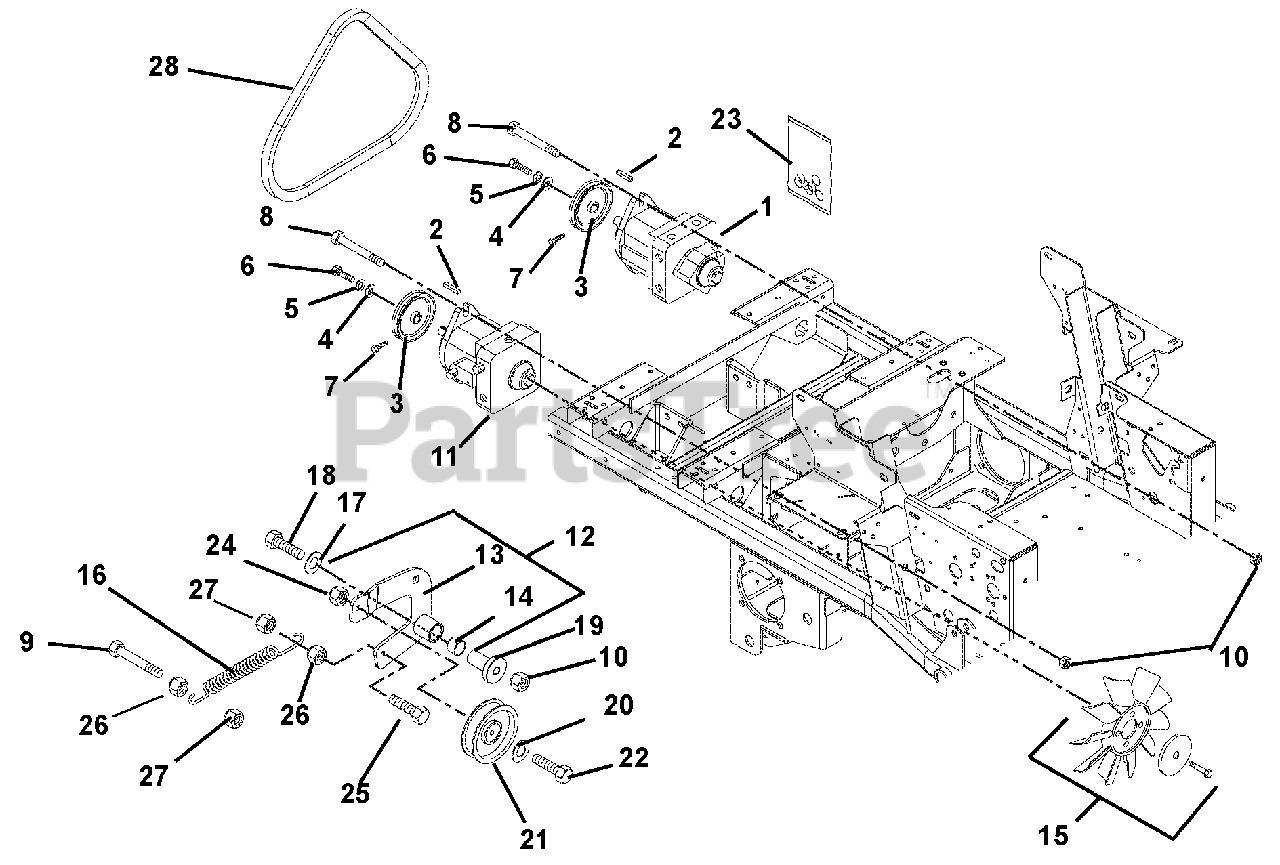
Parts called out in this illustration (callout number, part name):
1	Pump, Hydraulic (RTN) with Auxiliary
2	Key, Square 5 x 5 x 30mm Plain
3	Sheave, Poly-V .671 x 4.125
4	Washer, Flat-Steel .281 x 1.000 x .063
5	Washer, Locking .25 x .062
6	Bolt, Hex M6 x 1 x 16
7	Screw, Socket Head .25-20 x .50
8	Bolt, Hex .50-13 x 1.50 Grade 5
9	Bolt, Hex .31-18 x 2.50 Grade 5
10	Nut, Locking Top Flange .50-13
11	Pump, Hydraulic (RTN)
12	Assembly, Idler Arm Guard Drive (Includes 13 & 14)
13	Weldment, Idler Arm Ground Drive
14	Bushing, 1.00 x 1.125 x 1.936
15	Fan, Hydro Pump Cooling
16	Spring, Tension .120 x .845 x 6.500
17	Washer, Flat Steel .39 x.75 x.125
18	Bolt, Hex .50-13 x 3.50 Grade 5
19	Bearing, Pedestal
20	Washer, Flat Steel .406 x .812 x .065
21	Assembly, Idler 4"
22	Bolt, Hex .38-16 x 2.0 Grade 5
23	Kit, Pump Seal (One kit required for each pump)
24	Nut, Locking Top Flange .38-16
25	Bolt, Hex .31-18 x 1.25 Grade 5
26	Nut, Hex .31-18
27	Nut, Locking Top Flange .31-18
28	Belt, Poly-V 49.50, Hydrostatic 200Z Series
